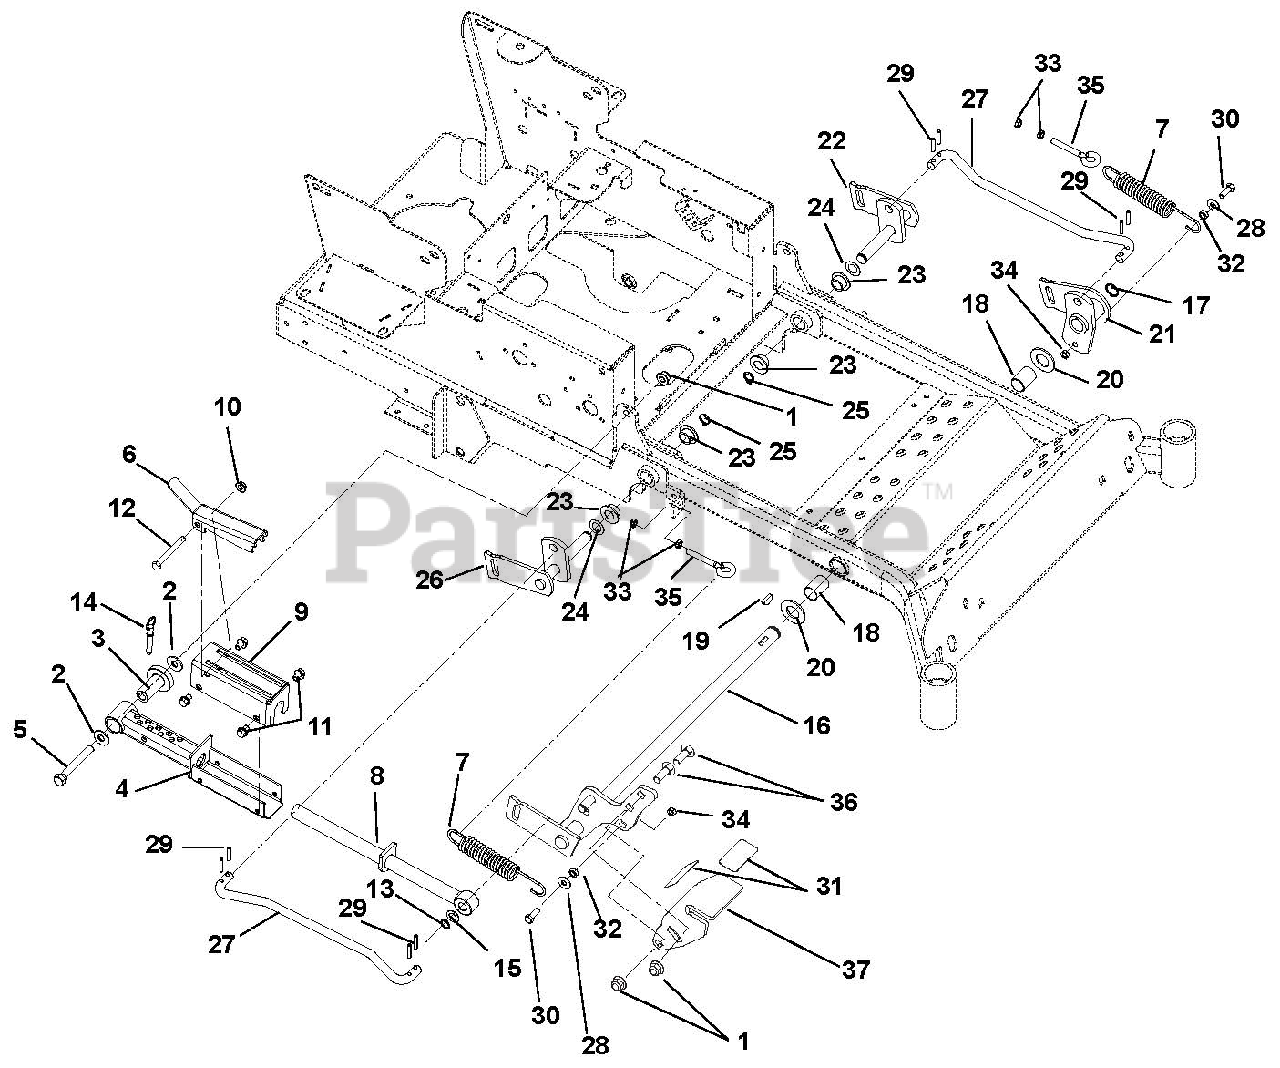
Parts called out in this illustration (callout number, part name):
1	Nut, Nyloc Top Flange .50-13
2	Washer, Flat Steel .531 x 1.25 x .10
3	Bearing, Pedestal
4	Weldment, Mechanical Lift
5	Bolt, Hex .50-13 x 3.75 Grade 5
6	Lock, Up, Mechanical Lift
7	Spring, Tension .162 x 1.25 x 8.25 Weldment 25
8	Weldment, Mechanical Lift Shaft
9	Weldment, Mechanical Lift Cover
10	Nut, Nyloc Flange 3/8-16
11	Screw, Tapping .38-16 x .50 Hex Washer Head
12	Bolt, Hex .38-16 x 3.25 Grade 5
13	Ring, Retaining External .625 x .050
14	Pin, Spring Ball .375 O.D. x 1.50
15	Washer, Flat Steel .630 x 1.005 x .062
16	Deck Lift
17	Ring, Retaining External 1.00 x .078
18	Bushing 1.00 ID x 1.125 OD x 1.50
19	Key, Woodruff .25 x 1.00
20	Washer, Flat Steel 1.062 x 2.0 x .134
21	Weldment, Left Hand Mower Lift Arm
22	Weldment, Left Hand Rear Mower Lift Arm
23	Bushing, Flange Nylon .762 x 1.0 x .580 x 1.48
24	Washer, Hardened Steel .758 x 1.23 x .031
25	Ring, Retaining External .689 x .077
26	Weldment, Right Hand Rear Mower Lift Arm
27	Rod, Lift Assist
28	Washer, Flat Steel .438 x 1.00 x .083
29	Pin, Roll .25 x 1.25 Stainless Steel
30	Bolt, Hex .38-16 x 1.00 Grade 5
31	Grip, Pedal
32	Bushing, Sleeve .377 x .624 x .235
33	Nut, Hex, Jam .375-16
34	Nut, Locking, Jam, Center .375-16
35	Bolt, Eye .375-16 x 2.50
36	Bolt, Round Hd.Square Neck .50-13 x 1.50 Grade 5 YZ
37	Foot Pedal, Adjustable Black
